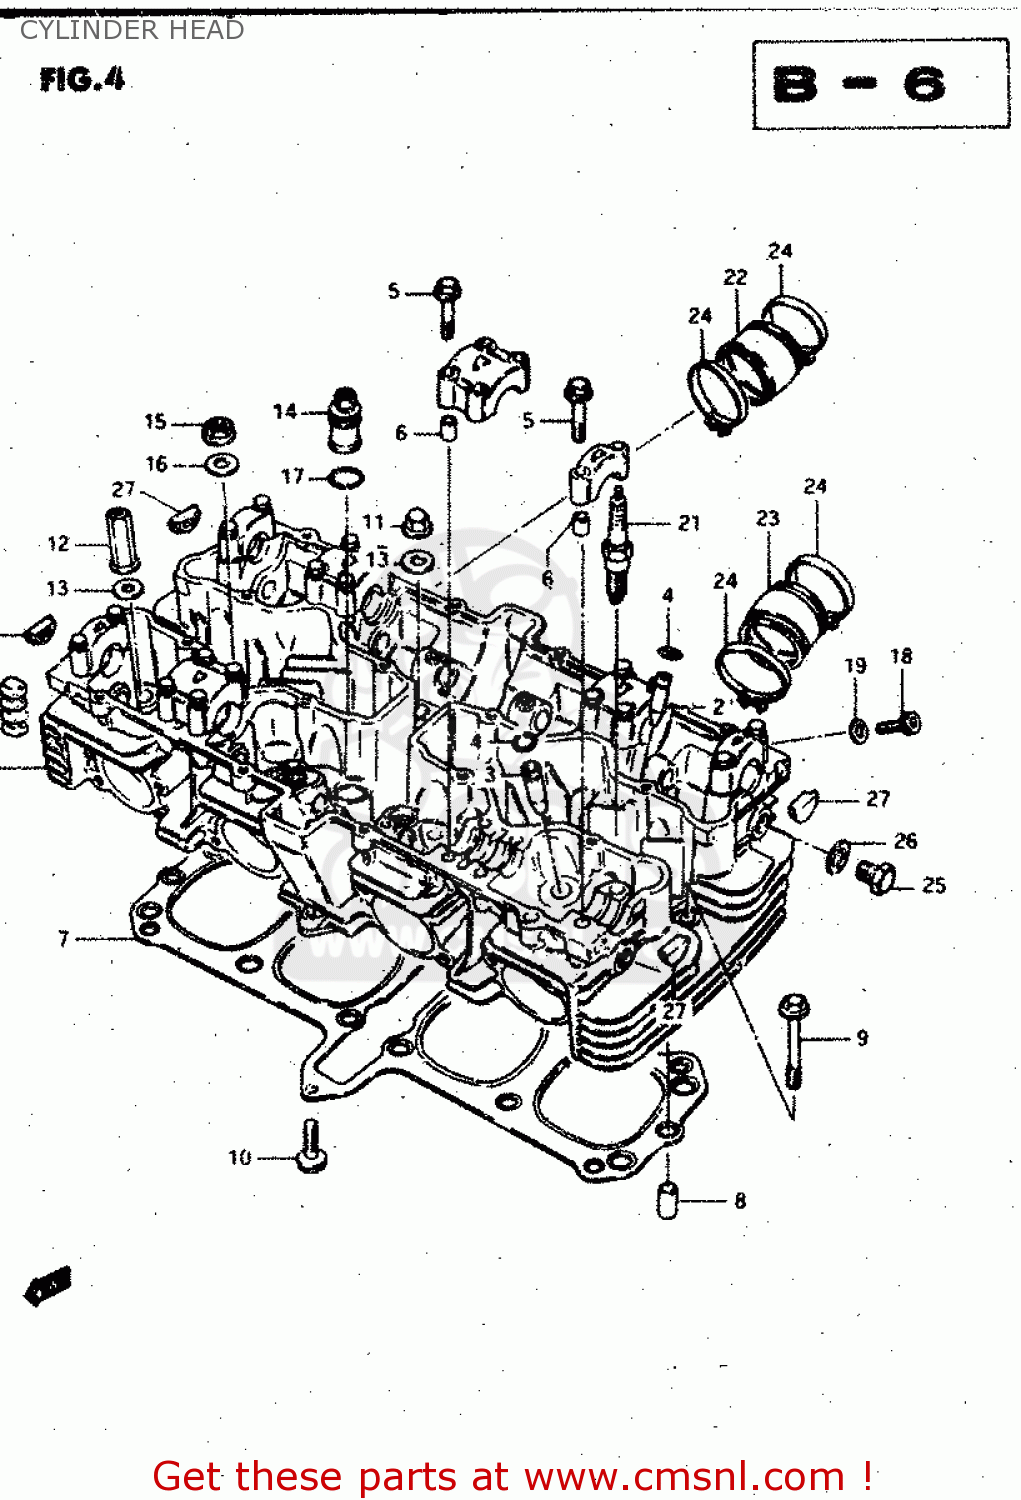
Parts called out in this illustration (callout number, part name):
1	HEAD ASSEMBLY,CYLINDER
2	GUIDE,INTAKE VALVE
3	GUIDE,INTAKE VALVE
4	RING,SNAP
5	BOLT(6X39)
6	PIN(6.2X8X11)
7	GASKET,CYLINDER HEAD (NAS)
8	PIN
9	BOLT
10	BOLT
11	NUT
12	NUT
13	GASKET(10.5X22X2) (NAS)
14	NUT,CYLINDER HEAD SEAL
15	NUT
16	WASHER(10.5X22X2.3)
17	O RING(D:2.4,ID:16.8)
18	BOLT
19	GASKET(5.3X9.3X1.2) (NAS)
20	PAD,CYLINDER
21	SPARK PLUG D8EA
22	PIPE,INTAKE,R
23	PIPE,INTAKE
24	CLAMP
25	PLUG (14X12)
26	GASKET(14X19.2X2) (NAS)
27	PLUG
